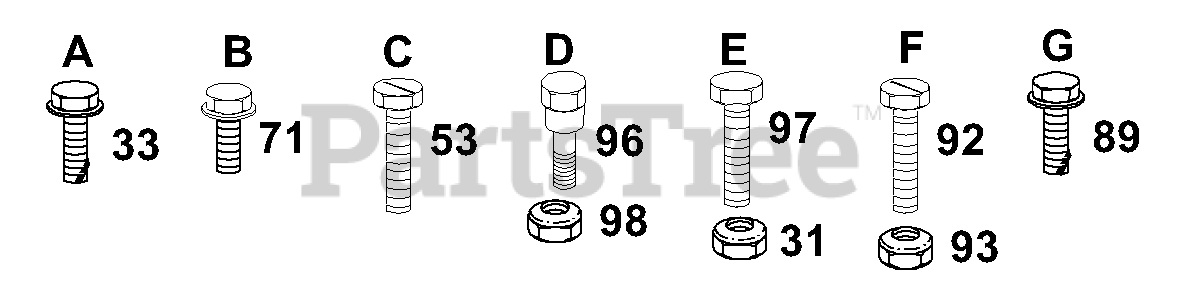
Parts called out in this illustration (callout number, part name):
31	Locknut 3/8-16
33	Screw, Hex Washer Thread Rolling 3/8-16 x 3/4
53	Screw, Special 3/8-16 x 3/4
71	Screw, Hex Washer Thread Rolling 5/16-18 x 1/2
89	Screw, Hex Washer Thread Rolling 5/16-18 x 3/4 Type TT
92	Screw, Hex Socket Hd. #10-24 UNC
93	Locknut #10-24 UNC
96	Bolt, Shoulder
97	Bolt, Hex, Fin 3/8-16 UNC x 1
98	Locknut 5/16-18
